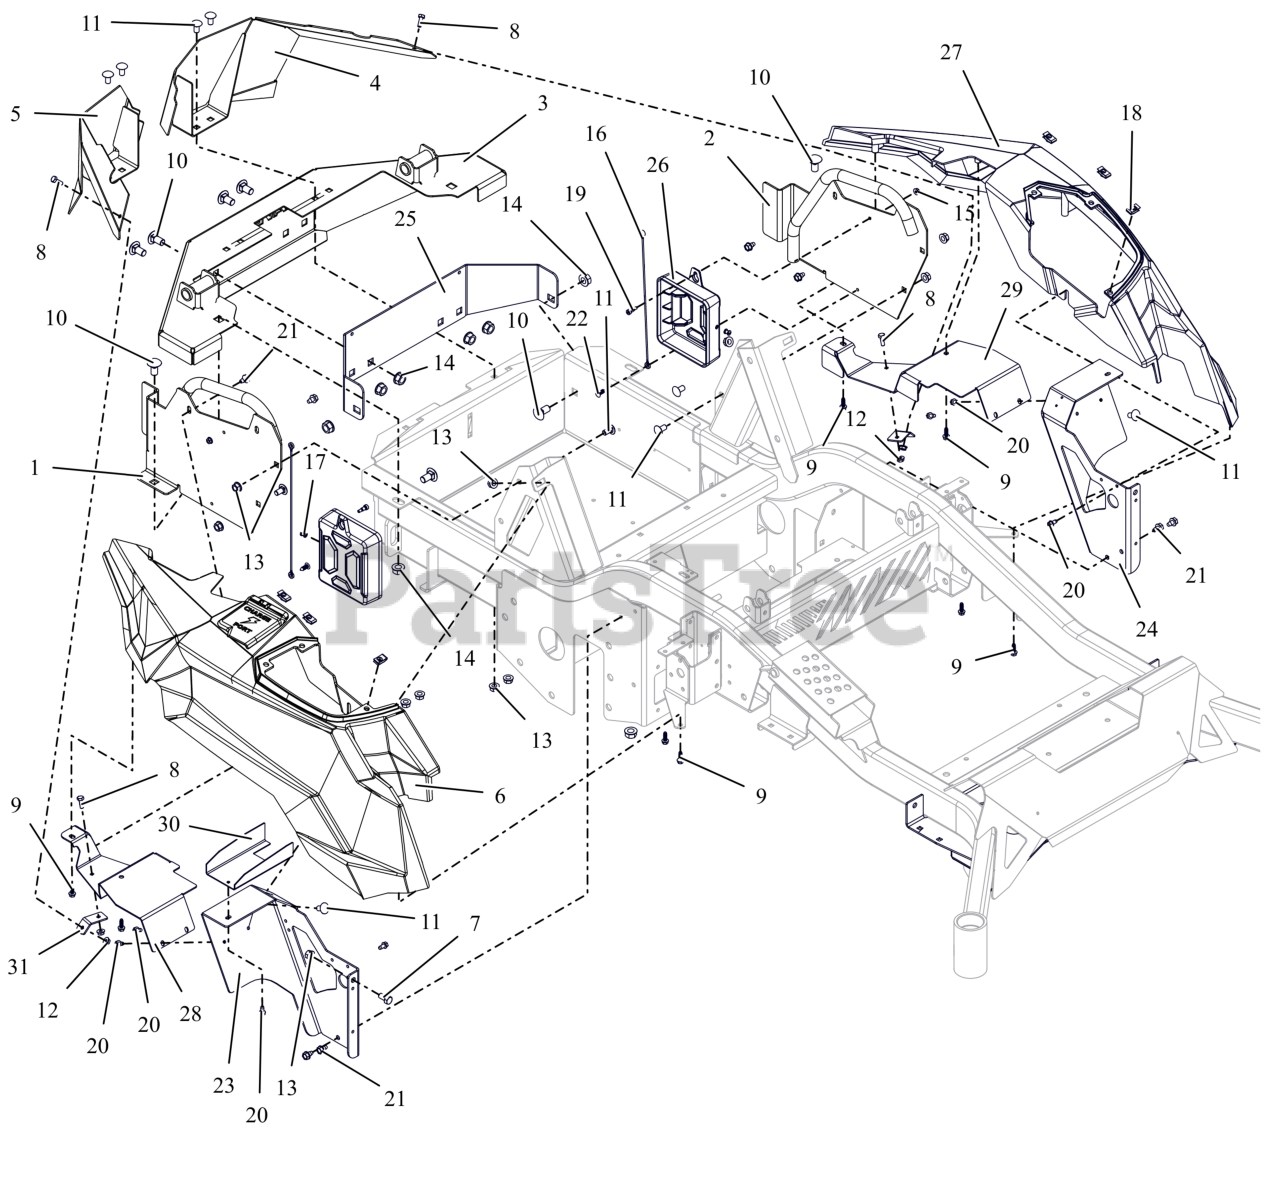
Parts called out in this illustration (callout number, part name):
1	WLDMT, REAR FENDER MOUNT-RH (RED)
2	WLDMT, REAR FENDER MOUNT-LH (RED)
3	WLDMT, BUMPER PT EV (RED)
4	WLDMT, REAR WRAP-LH (BLACK)
5	WLDMT, REAR WRAP-RH (BLACK)
6	ASM, FENDER RH PRO-TURN EV
7	BLT,HEX .38-16X.75 G5 ZCC
8	BLT, HEX .25-20X.75 G5 ZCC
9	SCR, PLASTITE-HWH 0.25 X 0.75 ZC120
10	BLT, RHSN .50-13X1.00 G5 ZCC
11	BTL,RHSSN .375-16 X 0.75 G5 FPB
12	NUT-LK-CTR-FLG .25-20 ZC120
13	NUT-LK-CTR-FLG .375-16 GF ZCC
14	NUT-LK-CTR-FLG .500-13 GG ZCC
15	NUT, FLG-TOP LK #10-24 GRF ZCC
16	CABLE, 12.0 LANYARD, NYLON
17	POST, & SCREW, PUSH LOCK .25 X .25
18	NUT-RTNR .25-20X.56
19	BLT-SHLDR .25X.375
20	SCR-TAP .25-20X.50 HWH ZCC
21	SCR,TAP .312-18X.50 HWH TR ZCC
22	RIVET, .25 NYLON PANEL
23	MOUNT, FRONT FENDER-RH
24	MOUNT, FRONT FENDER-LH
25	SUPPORT, BUMPER (BLACK)
26	COVER, BATTERY BUSBAR TERMINAL
27	FENDER, LH PRO-TURN EV
28	SHIELD, FENDER MOUNT -RH (BLACK)
29	SHIELD, FENDER MOUNT-LH (BLACK)
30	SHIELD, DEBRIS -CHARGE PORT (BLACK)
31	STRAP, SUPPORT - REAR WRAP (BLACK)
